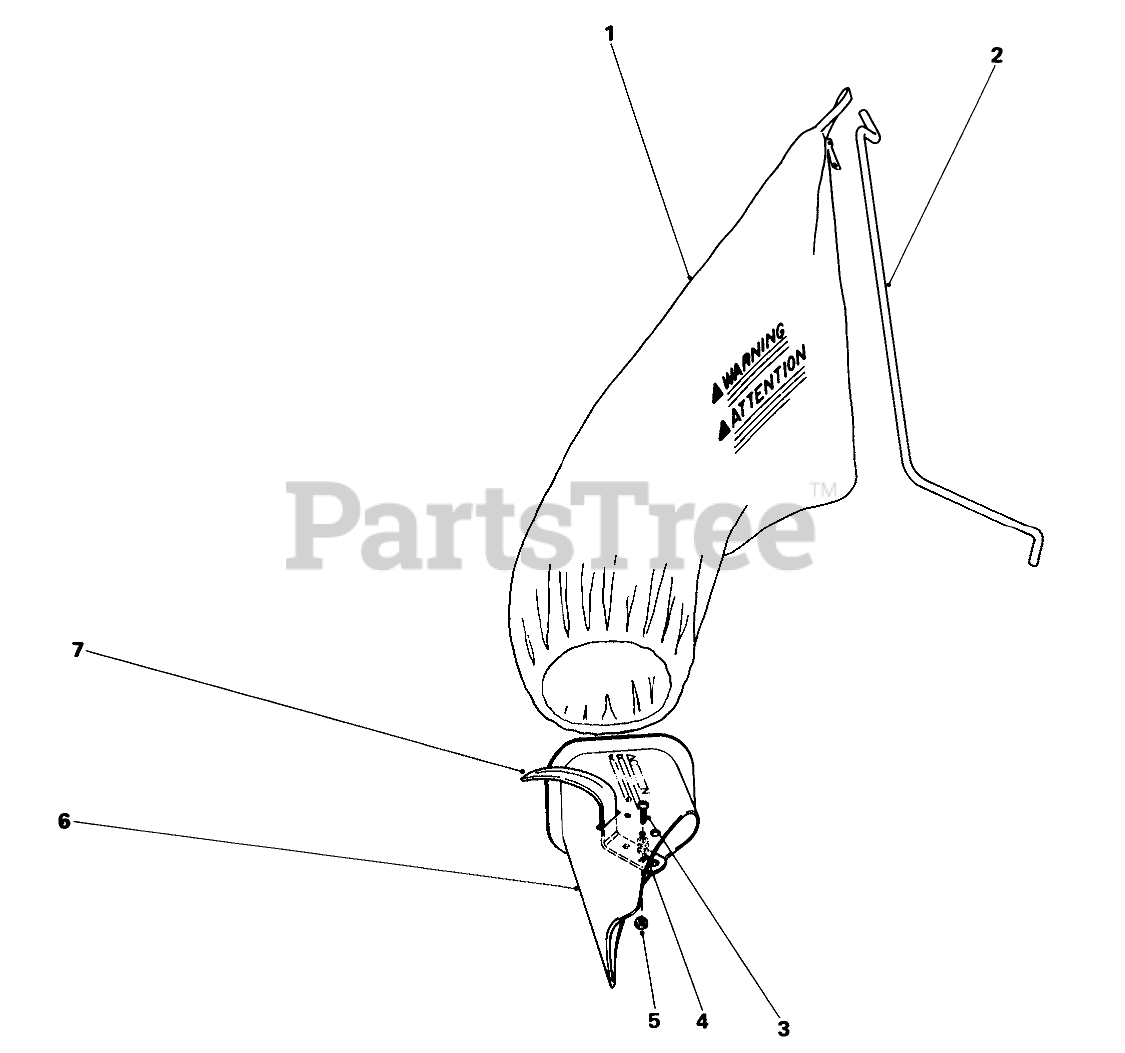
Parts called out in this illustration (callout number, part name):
1	BAG REPLACMNT44-0540
2	BAG HANGER ROD
4	WASHER-PLAIN
5	NUT-LOCK, SIDE
6	Grass Chute (Incl.Ref. #3-5 & 7)
7	CHUTE HANDLE
